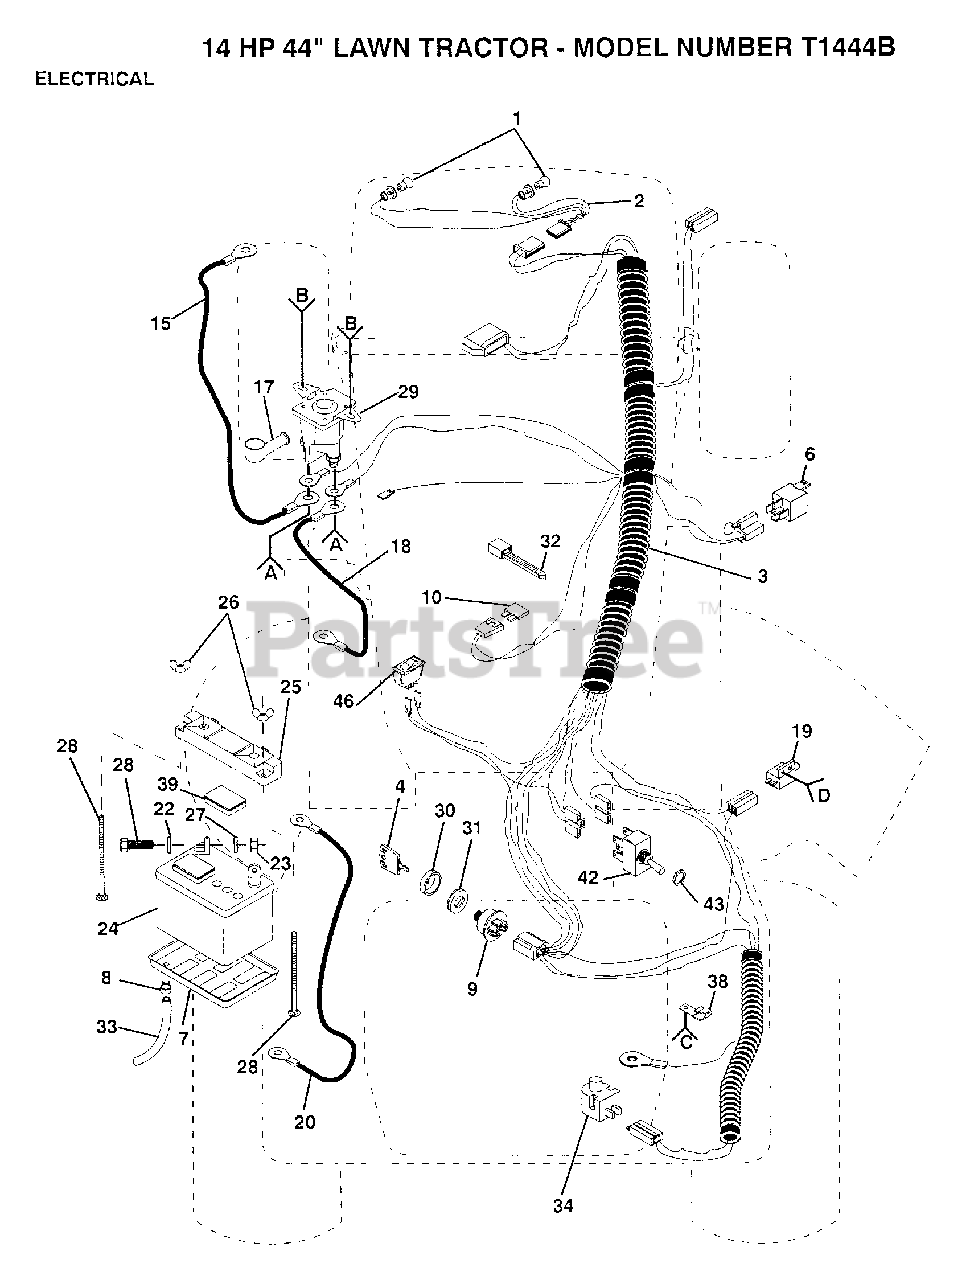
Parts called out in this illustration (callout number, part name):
2	HARNESS T
6	RELAY ASSY T
7	"TRAY T, BATTERY"
8	HOSE CLAMP T
10	FUSE HYT
18	STARTER CABLE GT
19	SWITCH-INTER. GT
22	WASHER
27	LOCKWASHER
28	BOLT
32	WIRE TIE
34	SWITCH SEAT
39	"CAP,BATTERY "
42	SWITCH T
43	HEX NUT T
